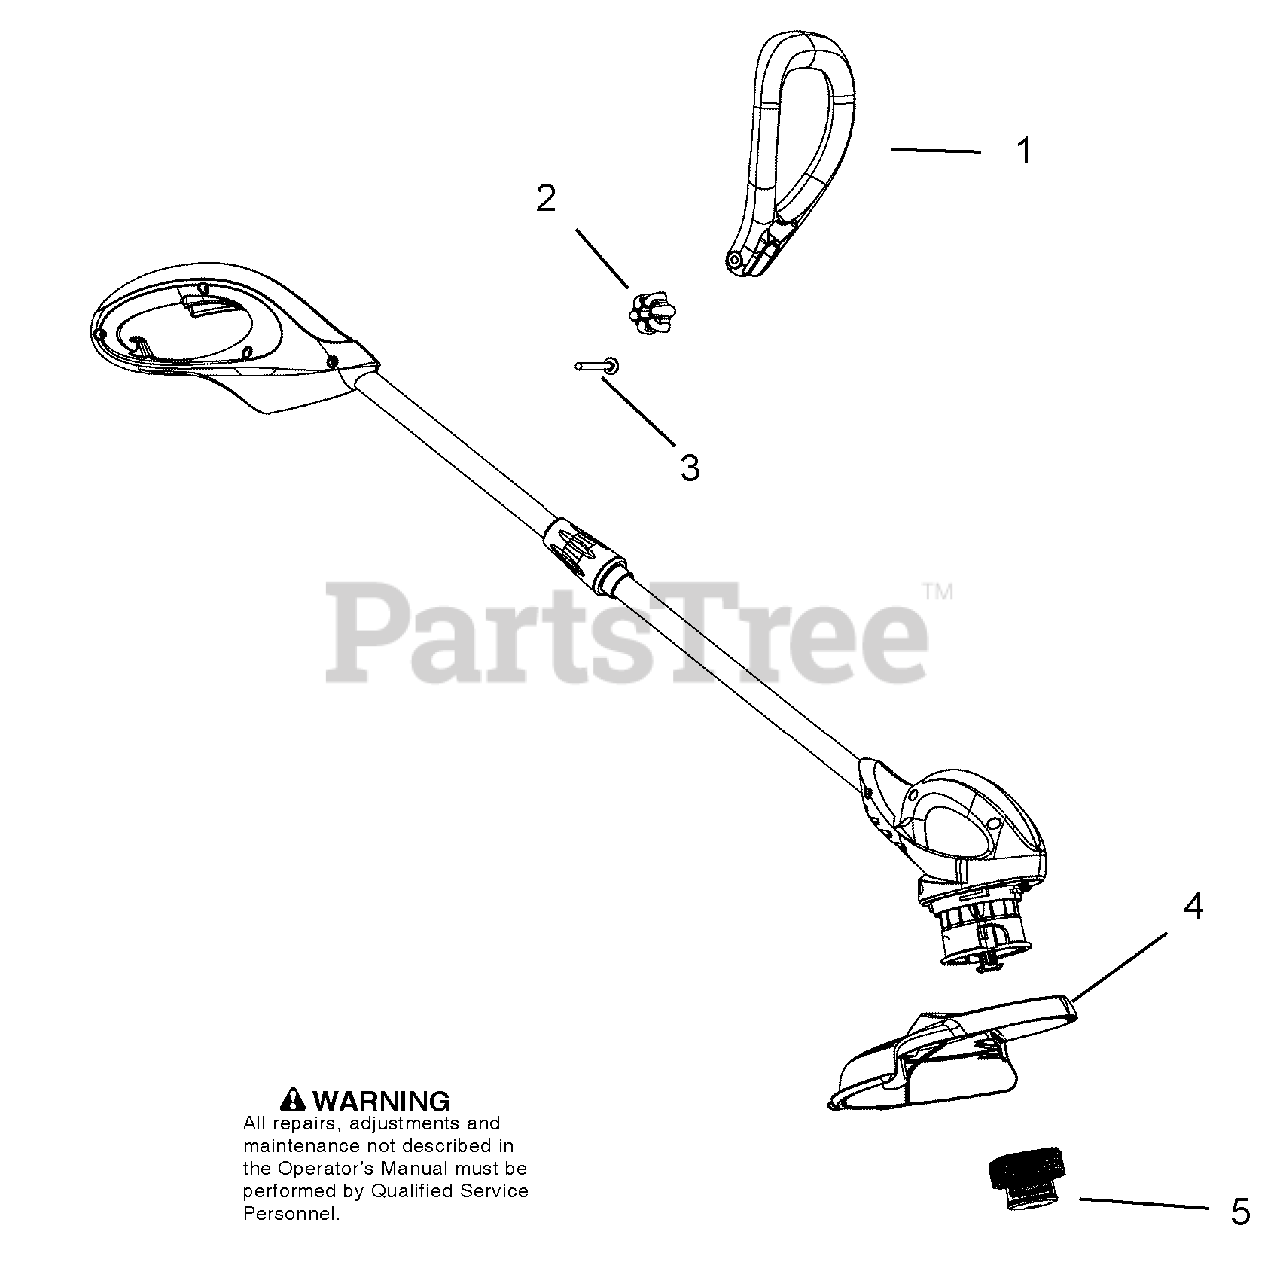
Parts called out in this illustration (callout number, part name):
1	Assit Handle
3	Bolt Carriage, M6 X 1
4	Shield Assembly
5	Spool with 0.065" Trimmer line
